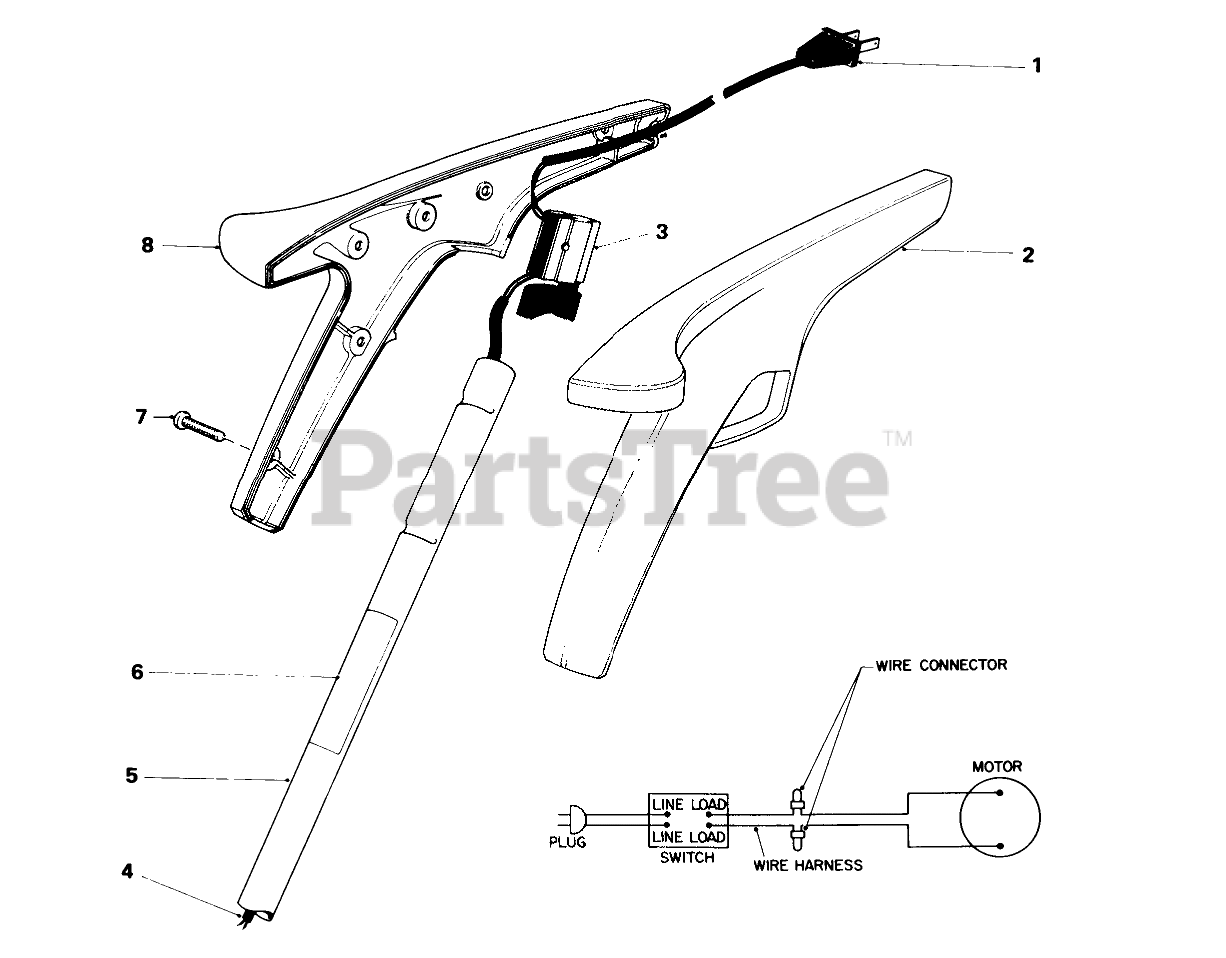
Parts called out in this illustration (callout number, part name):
1	Power Cord
2	LH HANDLE GRIP
3	SWITCH SINGLE SPEED
4	Wiring Harness
6	REP. SERIAL PLT
7	Screw
8	Grip-Right Hand
